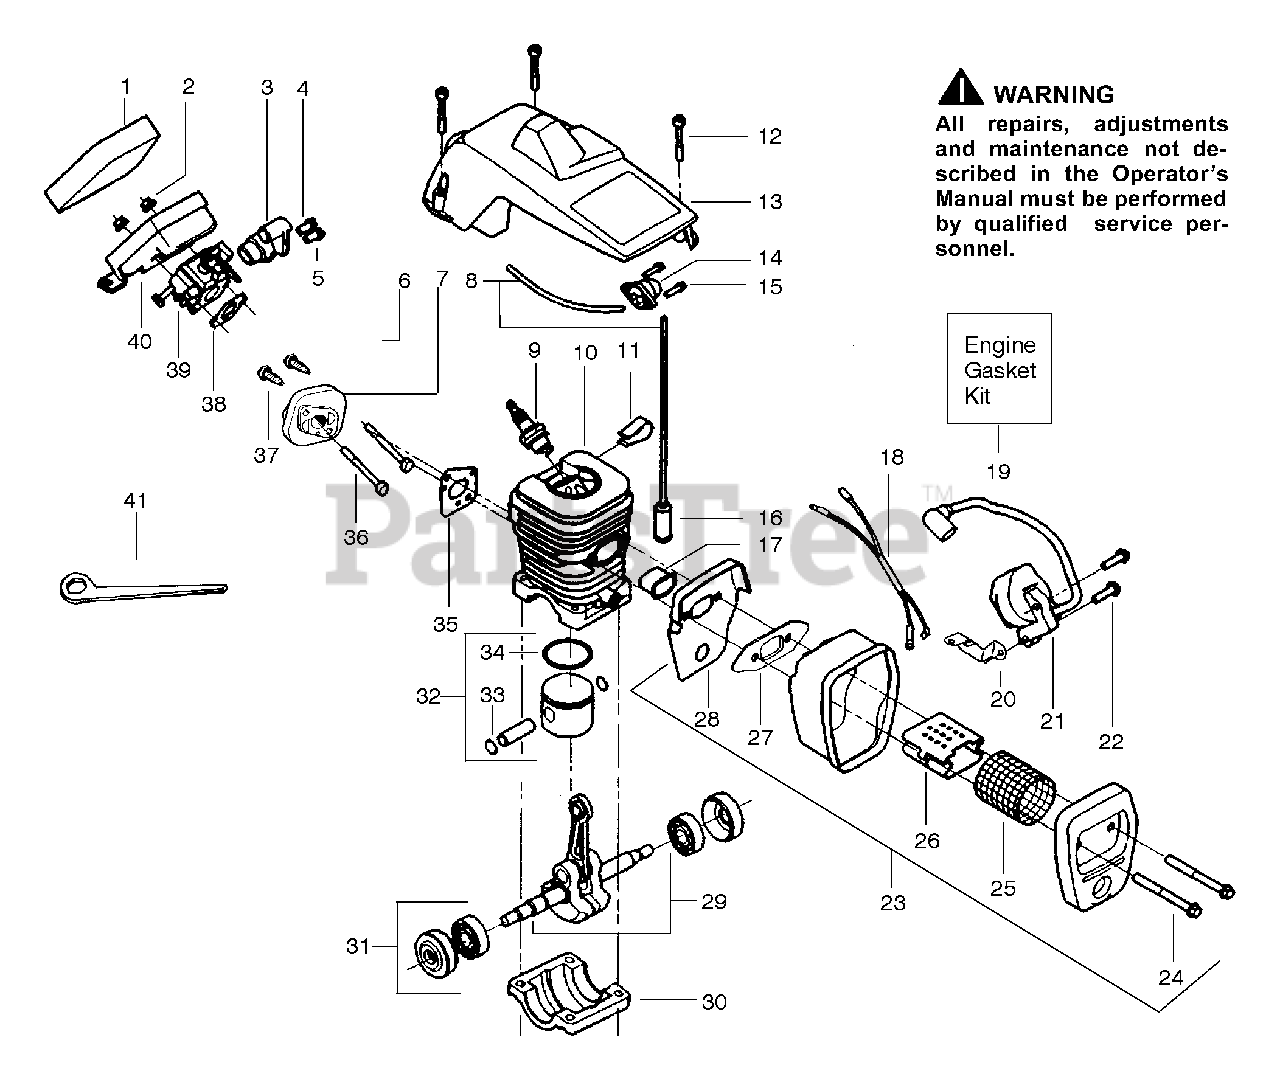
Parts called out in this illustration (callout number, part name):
1	Foam-Air Filter
3	Grommet-Carb Adjust
4	Limiter Cap-High
5	Limiter Cap-Low
6	Seal-Carb Adapter
7	Carb. Adapter
8	Kit-Fuel Line (Small)
9	Spark Plug (RCJ-7Y)
10	Kit-Cylinder
11	Clip-High Tension Lead
13	Shield-Cylinder
14	Assy-Air Purge
16	Assy-Fuel Pick-up
17	Insulator-Heat
18	Assy.-Wire Harness
19	Kit-Engine Gasket
20	Strap-Ground
21	Module-Ignition
23	Assy-Muffler
25	Screen-Spark
26	Diffuser-Muffler
27	Gasket-Muffler
28	Backplate-Muffler
29	Assy.-Crankshaft
30	Cap-Crankcase
31	Assy.-Seal & Bearing
32	Kit-Piston
33	Retainer-Piston Pin
34	Ring- Piston
35	Gasket-Carb. Adapter
38	Gasket-Carburetor
39	Kit-Carburetor
40	Housing-Air Filter
41	Wrench-Bar
